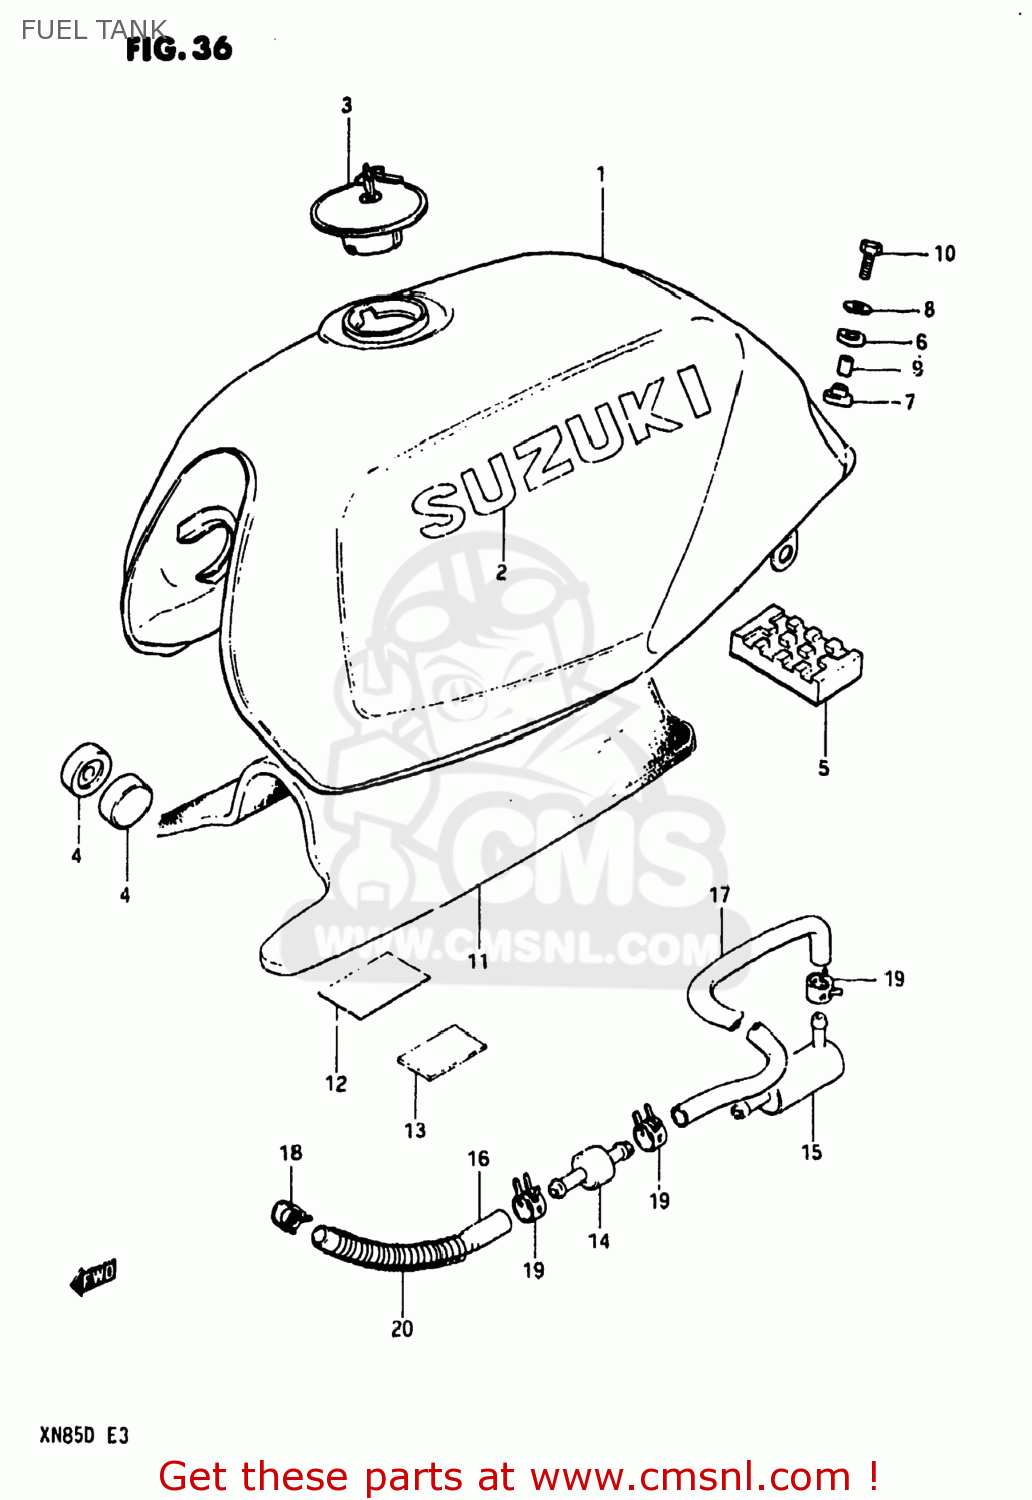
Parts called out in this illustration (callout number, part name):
1	TANK ASSEMBLY,FUEL
2	EMBLEM
3	CAP ASSEMBLY,FUEL TANK
4	CUSHION
5	CUSHION,FUEL TANK CTR
6	CUSHION
7	CUSHION
8	WASHER (6.5X24X1.6)
9	SPACER
10	BOLT
11	CUSHION, FUEL TANK INNER
12	TAPE,FUEL TANK CUSHION
13	PLATE,FUEL TANK CUSHION
14	CHECK VALVE,BREATHER
15	CANISTER, BRETHER HOSE
16	HOSE
17	HOSE
18	CLAMP
19	CLAMP
20	SPRING
